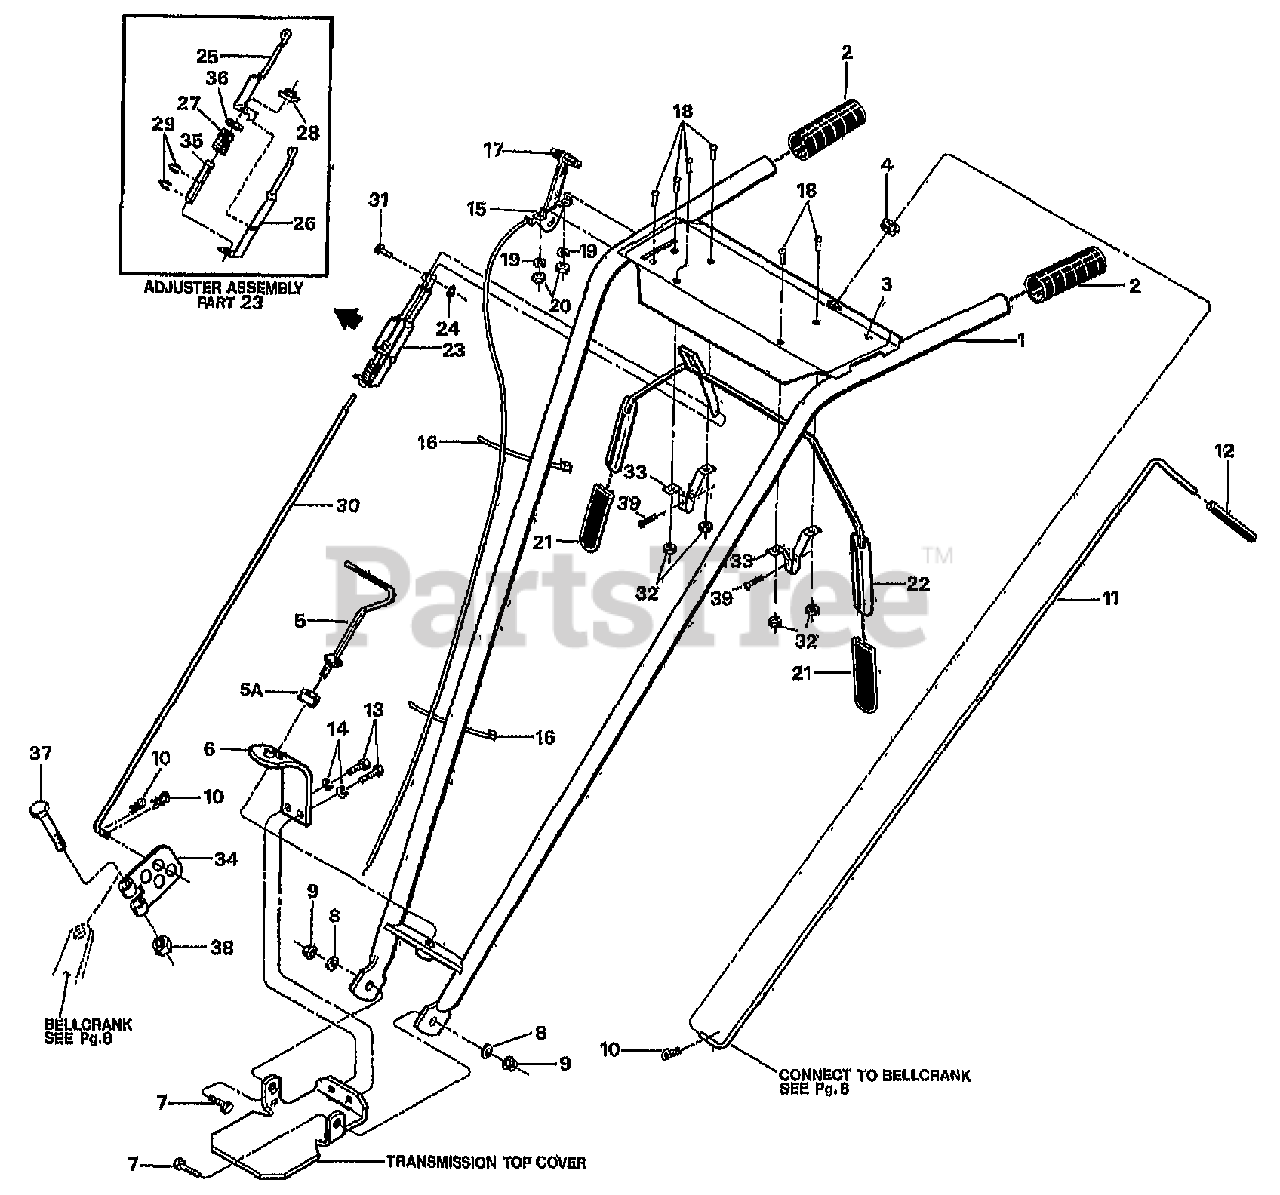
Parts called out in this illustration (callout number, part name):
1	ASSM-HANDLEBAR W/GRIPS (INCL. 2-5A)
2	GRIP-H/B 1" PONY/P-J OPC
3	DECAL-CONTROL PANEL OPC
4	BUSHING-NYLON (PART OF OPER. CONTROL PANEL)
5	ASSM-STUD H/B
5A	WASHER-1.0X.38X.375
6	PLATE-HANDLEBAR ADJUST
7	SCR-HH 3/8-16X1.0 G5 ZP (HANDLEBAR ATTACH.)
8	WASHER-FLAT 3/8 SAE (HANDLEBAR ATTACH.)
9	NUT-LOCK 3/8-16 NYLON ZP (HANDLEBAR ATTACH.)
10	PIN-CLIP (CONN #11 & FRWD CLTCH TO SHFT MECH)
11	ROD-REV W/GRIP OPC (INCL. GRIP #9198)
12	GRIP-CONTROL ROD
13	SCR-HH 3/8-16X.75 (HANDLEBAR ATTACH.)
14	WASHER-LK .375 (HANDLEBAR ATTACH.)
15	CABLE-THROTTLE JR OPC
16	TIE-RED (ATTACH. THROTTLE CABLE TO HANDLEBAR)
17	KNOB-THROTTLE CABLE
18	SCR-RH M10-32X.5 MACH
19	WASHER-LK M10
20	NUT-HH M10-32X.125
21	GRIP-PADDLE SM FRAME OPC
22	BAIL, OPC (W/ 2 #9390 GRIPS)
23	ASSM-ADJUSTMENT OPC (INCL. #25-27, 29 & 36)
24	RING-KLIP .188 DIA
25	ADJUSTER-RT SIDE OPC
26	ADJUSTER-LT SIDE OPC
27	SPRING-ADJUSTER OPC
28	WELDNUT 5/16-18
29	RING-KLIP .500 ZINC
30	ROD-CONTROL OPC
31	ASSM-PIN & CLIP (SMALL FRAME)
32	NUT W/LKWASHER #10-32 ZP
33	BRACKET-BAIL OPC
35	BUSHING-.5X.334X2.88
36	WASHER-.75X.51X.06 ZP
37	SCR-HH 1/4-20X1.5 G5ZP
38	NUT-LK 1/4-20
39	SCR-HWH 1/4-20 X .5 STH
